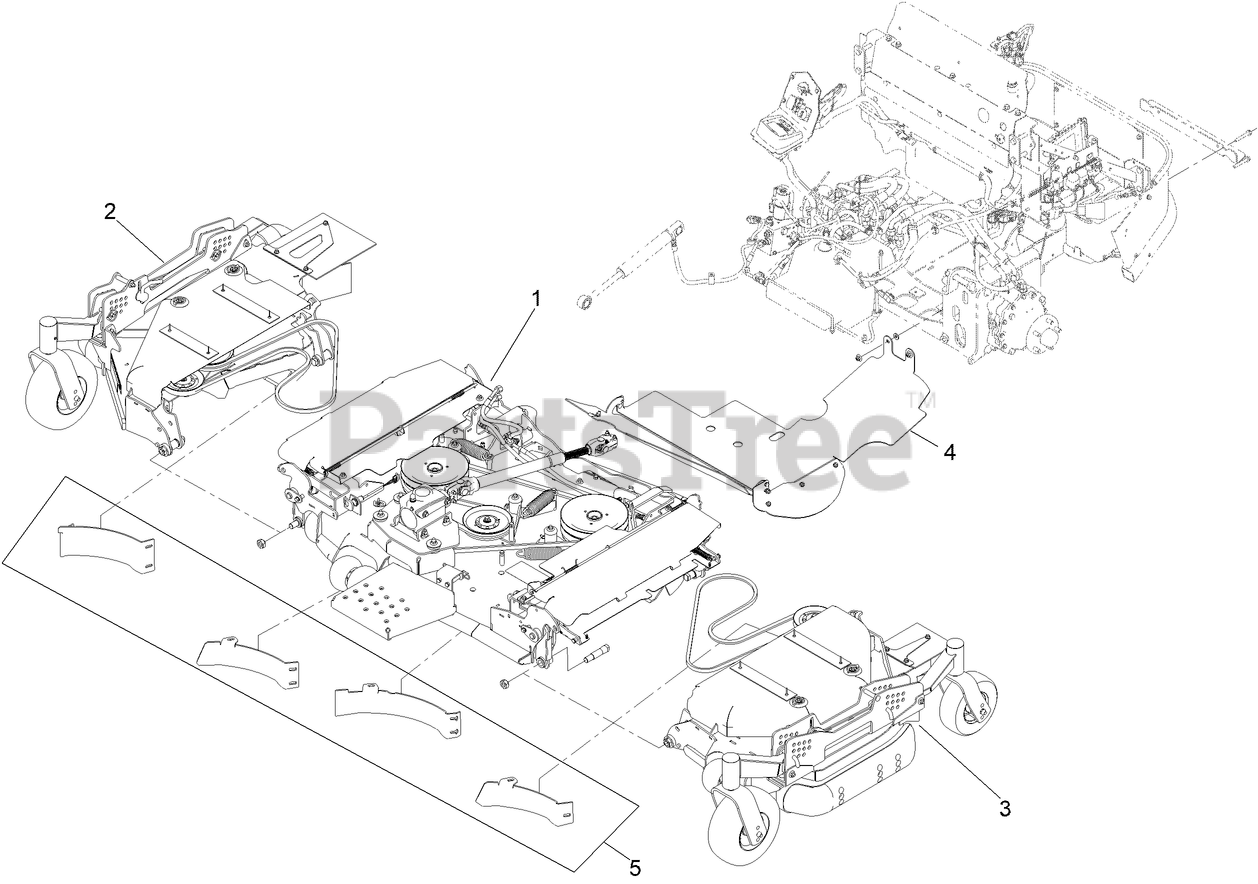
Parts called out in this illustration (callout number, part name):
1	ASM-DECK, CTR
2	ASM-DECK, RH WING
3	ASM-DECK, LH WING
4	DISCHARGE TUNNEL ASM
5	KIT-96RD MULCH
